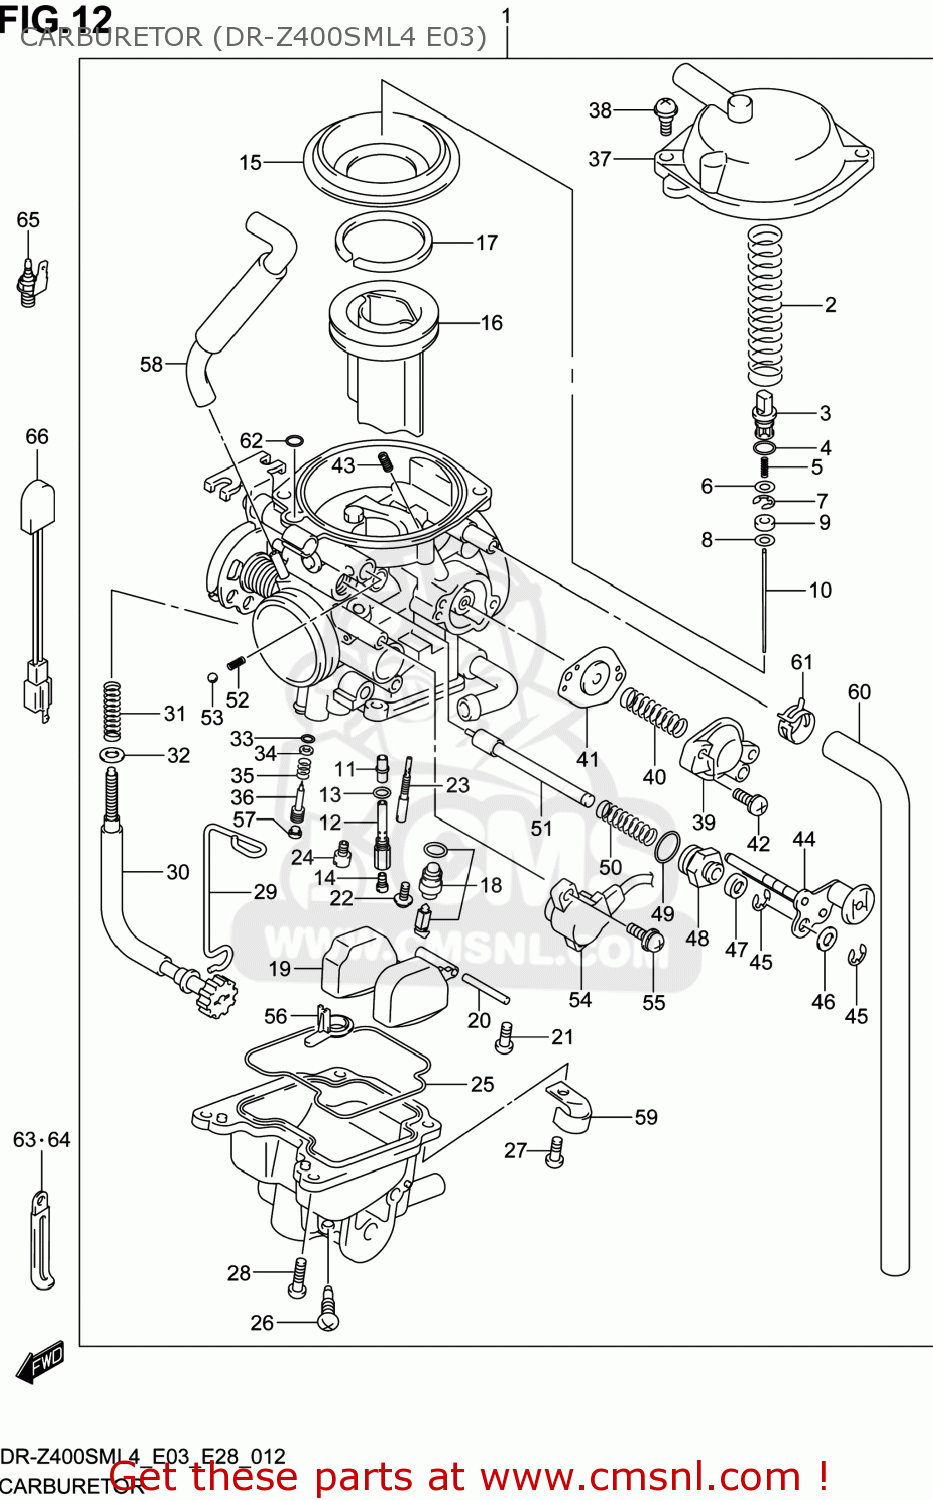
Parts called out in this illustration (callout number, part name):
1	CARBURETOR ASSY
2	SPRING
3	HOLDER
4	O RING(D:1.9,ID:4.8)
5	SPRING
6	WASHER
7	E RING,MULTIPLE JET NOZZLE
8	RING
9	WASHER
10	NEEDLE,JET
11	JET
12	HOLDER,JET
13	O RING
14	JET,MAIN(142.5)
15	DIAPHRAGM
16	VALVE,PISTON
17	RING
18	VALVE ASSY,NEEDLE
19	FLOAT ASSY
20	PIN,FLOAT
21	SCREW
22	SCREW
23	JET,PILOT(22.5)
24	JET,MAIN(62.5)
25	GASKET (NAS)
26	SCREW,DRAIN
27	SCREW
28	SCREW
29	CLIP
30	SCREW,ADJUST
31	SPRING,THROTTLE SCREW
32	WASHER,STARTER SHAFT
33	O RING,PILOT AIR SCREW
34	WASHER
35	SPRING,THROTTLE SCREW
36	ADJUSTER
37	COVER ASSY,DIAPHRAGM
38	SCREW
39	COVER ASSY
40	SPRING
41	DIAPHRAGM ASSY
42	SCREW
43	JET,POWER(135)
44	PLATE ASSY
45	E RING
46	WASHER
47	CAP,STARTER VALVE
48	GUIDE SCREW,PLUNGER
49	O RING
50	SPRING
51	PLUNGER ASSY
52	SPRING
53	BALL,CARBURETOR
54	SENSOR ASSY
55	SCREW
56	RING
57	PLUG
58	HOSE
59	PLATE
60	HOSE,AIR VENT(6.5X10.5)
61	CLIP
62	O RING
63	CLAMP(L:45)
64	CLAMP(L:120 T:1.0)
65	HEATER ASSY,CARBURETOR(15W)
66	THERMO SWITCH,CARB HEATER
